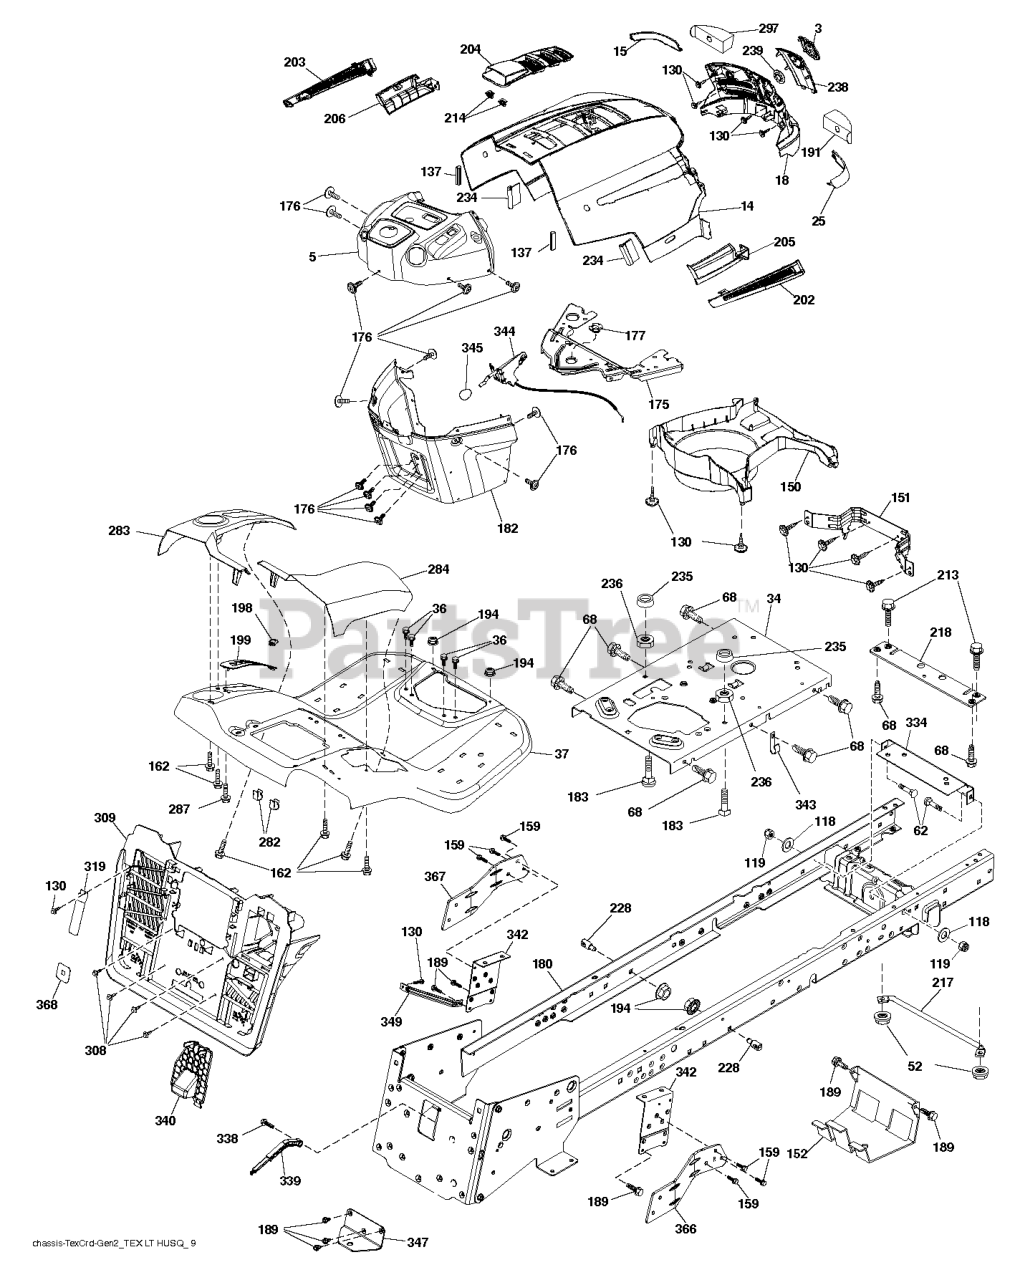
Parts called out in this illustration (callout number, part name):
3	LOGO.HUSQ.GT.LT.CROWN.H
5	SUBASM.DASH.UPPER.HLT.498
14	HOOD.HUSQVARNA.LT.ORANGE
15	LENS.HUSQVARNA LT.RH
18	GRILLE.SVC.HUSQVARNA.GREY
25	LENS.HUSQVARNA LT.RH
34	PLATE.ENGINE.10GA.CRD.GENII
36	SCREW 5/16"
37	FENDER.TEX.SRD.CRD.FRN.GUARDS
52	LOCKNUT
62	BOLT D
68	Screw 5/16-18 x 1/2 Hex, Self Tapping 5/16-18 x 1/2
118	WASHER
130	SCREW.#10 X 0.750.BOS
137	BUMPER DASH
151	BRACKET PIVOT
152	SHIELD.BROWNING.W/TEX
159	SCREW, 3/8-16X3/4
162	SCREW.HI-LO.CONSOLE
175	CROSSMEMBER
176	SCREW.#10-24X5/8.RN.QU
177	BUSHING STEERING
180	WELDMENT.CHASSIS.TEX.CRD.GEN.2
182	DASH DASH. LOWER. PREDATOR. LT
183	BOLT.5/16-18X1-1/4 FULL THD
189	SCREW
191	INSERT.REFLECTIVE.RH.
194	NUT LOCK HEX FLANGE 5/16-18
198	INDICATOR.DECK.LIFT.RED
199	PLATE DECK LIFT
202	VENT.SIDE.HUSQVARNA.LT.RT
203	VENT.SIDE.HUSQVARNA.LT.LFT
204	SUBASM.TOP.VENT.HUSQ.LT
205	SKIRT.SIDE.HUSQVARNA.LT.RT
206	SKIRT.SIDE.HUSQVARNA.LT.LEFT
213	BOLT
214	CLIP.RETAINER.TINNER.
217	ROD.PIVOT.HOOD
218	X-PIECE.HOOD.STOP.NON/
228	STUD.FASTNER.W/ANTI-ROTATE
234	BUMPER.HOOD.TEX.HUSQVARNA
235	SPACER FENDER
236	NUT.CENTERLOCK.5/16-
238	TRIM.HUSQ LT.668
282	CLIP.RETAINER.CONSOLE.LT.HUSQ
283	CONSOLE.DECKLIFT.CRDII.498
284	CONSOLE.PEDAL.HYDRO
287	SCREW 1/4X20
297	INSERT REFLECTIVE
308	BOLT.5/16-18UNCX3/4 W/SEMS.BLK
309	BACKPLATE.ASM.CRDII.ANTIROTAT
319	LEVER.BAG.CRDII.ANTIROTATION
334	BRACKET.ENGINE
338	BOLT BOLT SHOULDER
339	LEVER LEVER BAGGER
340	BATTERY.DOOR.TEX.CRD.GEN.2,1
342	SUPPORT SUPPORT FENDER
343	CLIP CLIP
344	CONTROL.EZ.MULCH.TEX/CRD
345	RP KNOB.OVAL.TAPERED.3/8-16BLK
347	HITCH TOW
349	BRACKET.SUPPORT.LRVB/CRD
366	BRACKET.RH.FRONT.BAGGER.BLACK
367	BRACKET.LH.FRONT.BAGGER.BLACK
368	FULL.LEVER.BAGGER.TEX.CRD
